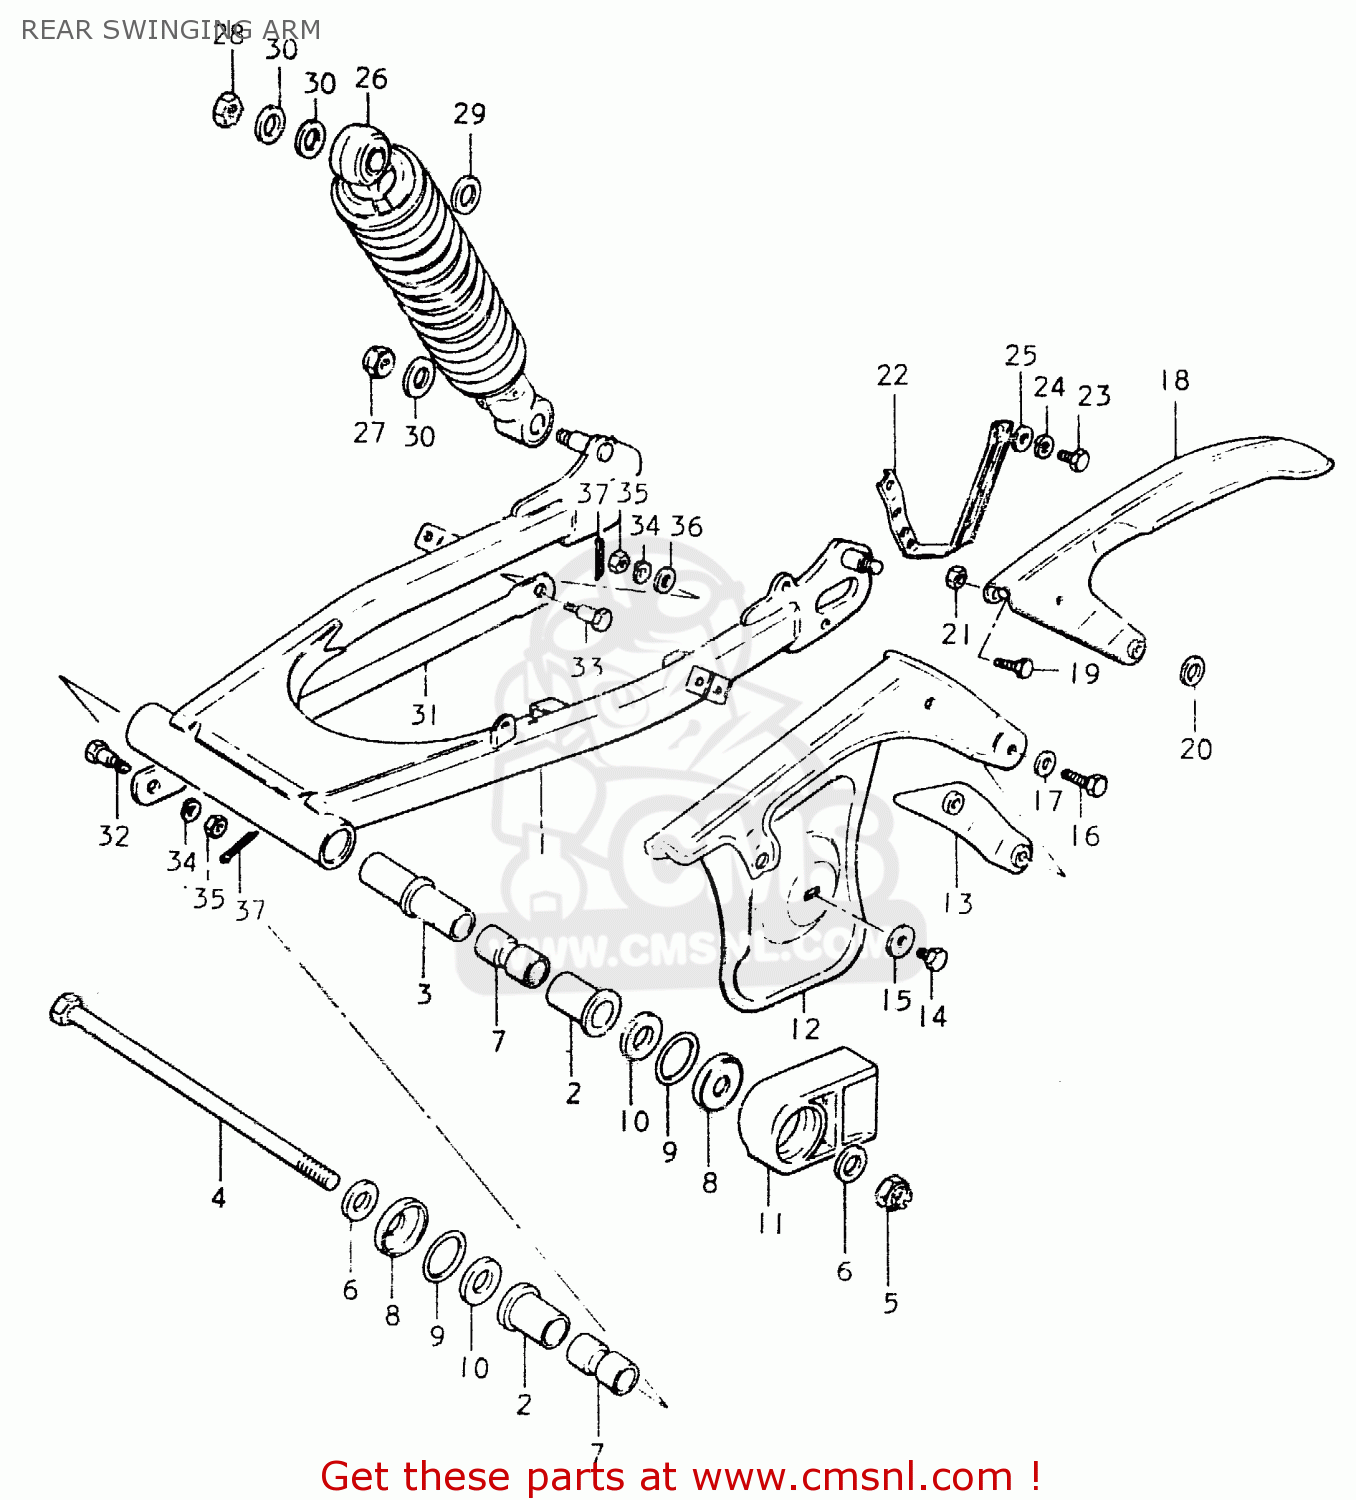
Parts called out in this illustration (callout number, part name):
1	SWINGING ARM SET
2	BUSH
3	SPACER,RR SWGARM PIVOT CTR
4	SHAFT,REAR SWING ARM
5	NUT 12MM
6	WASHER
7	SPACER,RR SWGARM PIVOT
8	COVER,SWGARM BUSH DUST SEAL
9	O RING(D:2,ID:24.5)
10	WASHER(12.5X24X2.3)
11	BUFFER,CHAIN TOUCH DEFENSE
12	CASE,CHAIN
13	REINFORCEMENT,CHAIN CASE
14	BOLT(6X8)
15	WASHER
16	BOLT, UPPER
17	WASHER
18	CHAIN CASE, END
19	BOLT
20	WASHER
21	NUT
22	GUIDE,CHAIN
23	BOLT 8X12
24	LOCK WASHER
25	WASHER
26	ABSORBER ASSY,RR SHOCK
27	NUT, LOWER LH
28	NUT
29	WASHER
30	WASHER
31	TORQUE LINK,REAR
32	BOLT(8X22)
33	BOLT(8X26.5)
34	LOCK WASHER
35	NUT
36	WASHER
37	PIN
